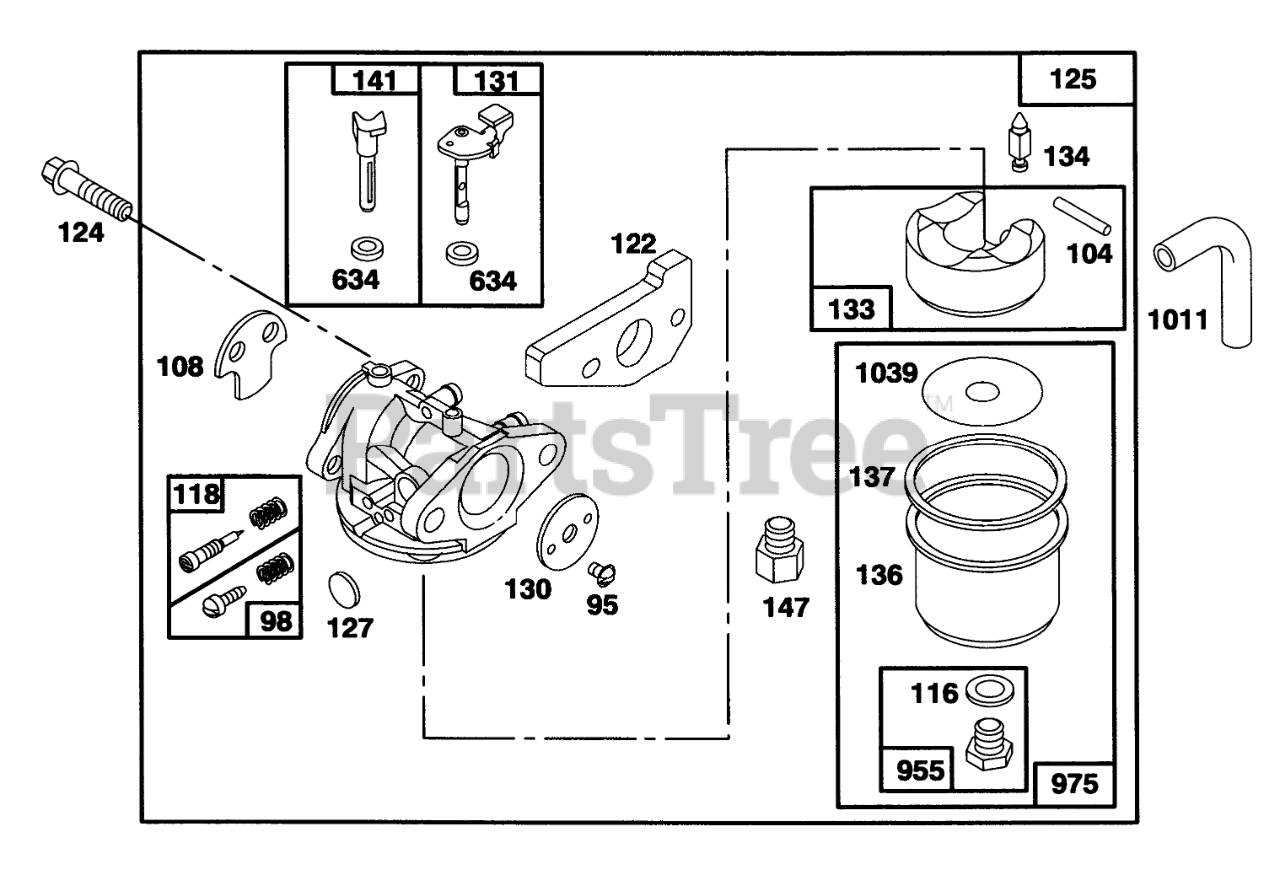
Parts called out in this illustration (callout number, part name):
33	EXHAUST VALVE
95	SCREW - ROUND HEAD
98	IDLE ADJUSTING SCREW
104	FLOAT HINGE PIN
108	CHOKE VALVE
116	SEALING GASKET
118	VALVE KIT - NEEDLE
122	ADAPTER ASSEMBLY
124	HEX HEAD SCREW
125	CARBURETOR ASSEMBLY
127	PLUG
130	THROTTLE VALVE
131	THROTTLE SHAFT
133	FLOAT-CARBURETOR
134	Valve-Inlet (Includes Seat)
136	FLOAT BOWL
137	FLOAT BOWL GASKET
141	CHOKE SHAFT
147	JET ADAPTER
634	SEAL WASHER
955	HEX HEAD SCREW
975	CARBURETOR BOWL ASM
1011	VENT TUBE
1039	FLOAT LIMITER
